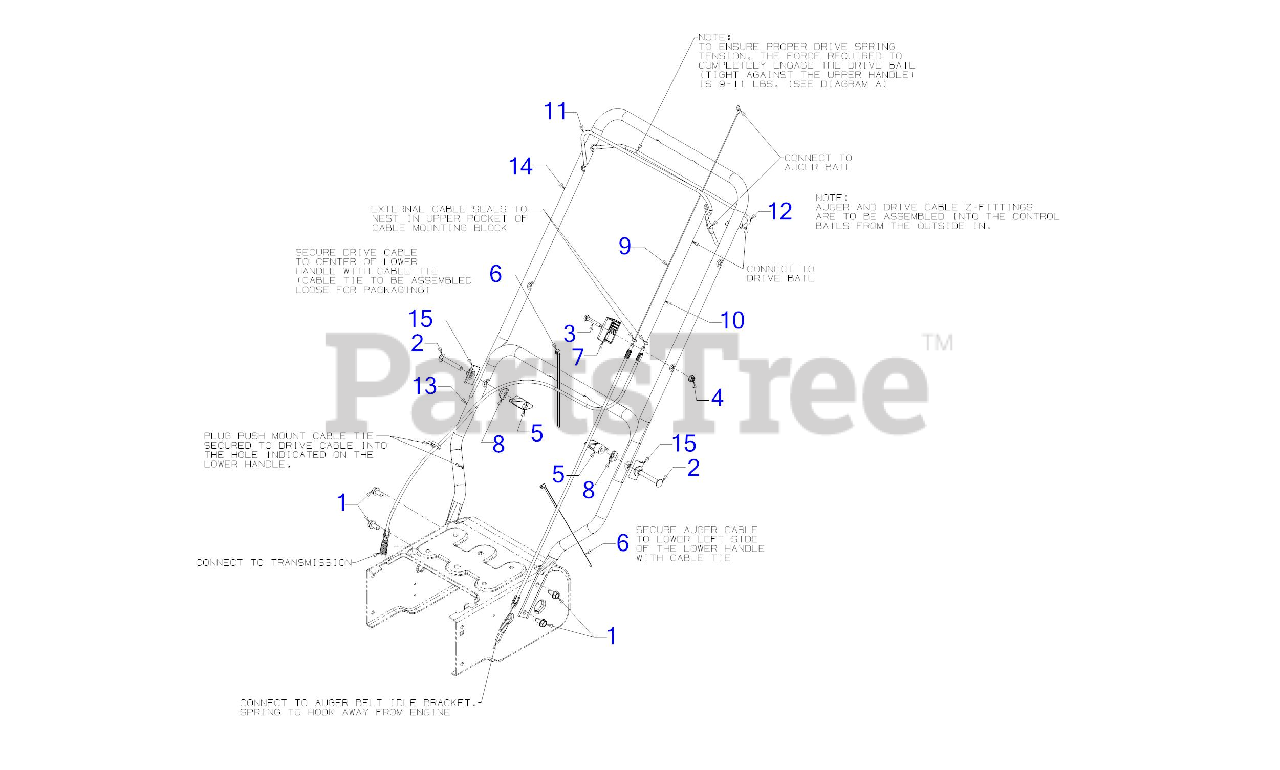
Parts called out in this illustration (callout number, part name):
1	SCREW 5/16-18 x .750
2	SCRE W5/16-18 x 2.25 GR5
3	SCREW 1/4-20 x 1.50 GR.5
4	FLANGE LOCK NUT
5	KNOB ASSEMBLY-W/NUT
6	7" CABLE TIE
7	CABLE MOUNT
8	SADDLE WASHER
9	AUGER CLUTCH CABLE
10	TRANSMISSION CLUTCH CABLE
12	DRIVE BAIL
13	LOWER HANDLE
14	UPPER HANDLE
15	HANDLE TAB
